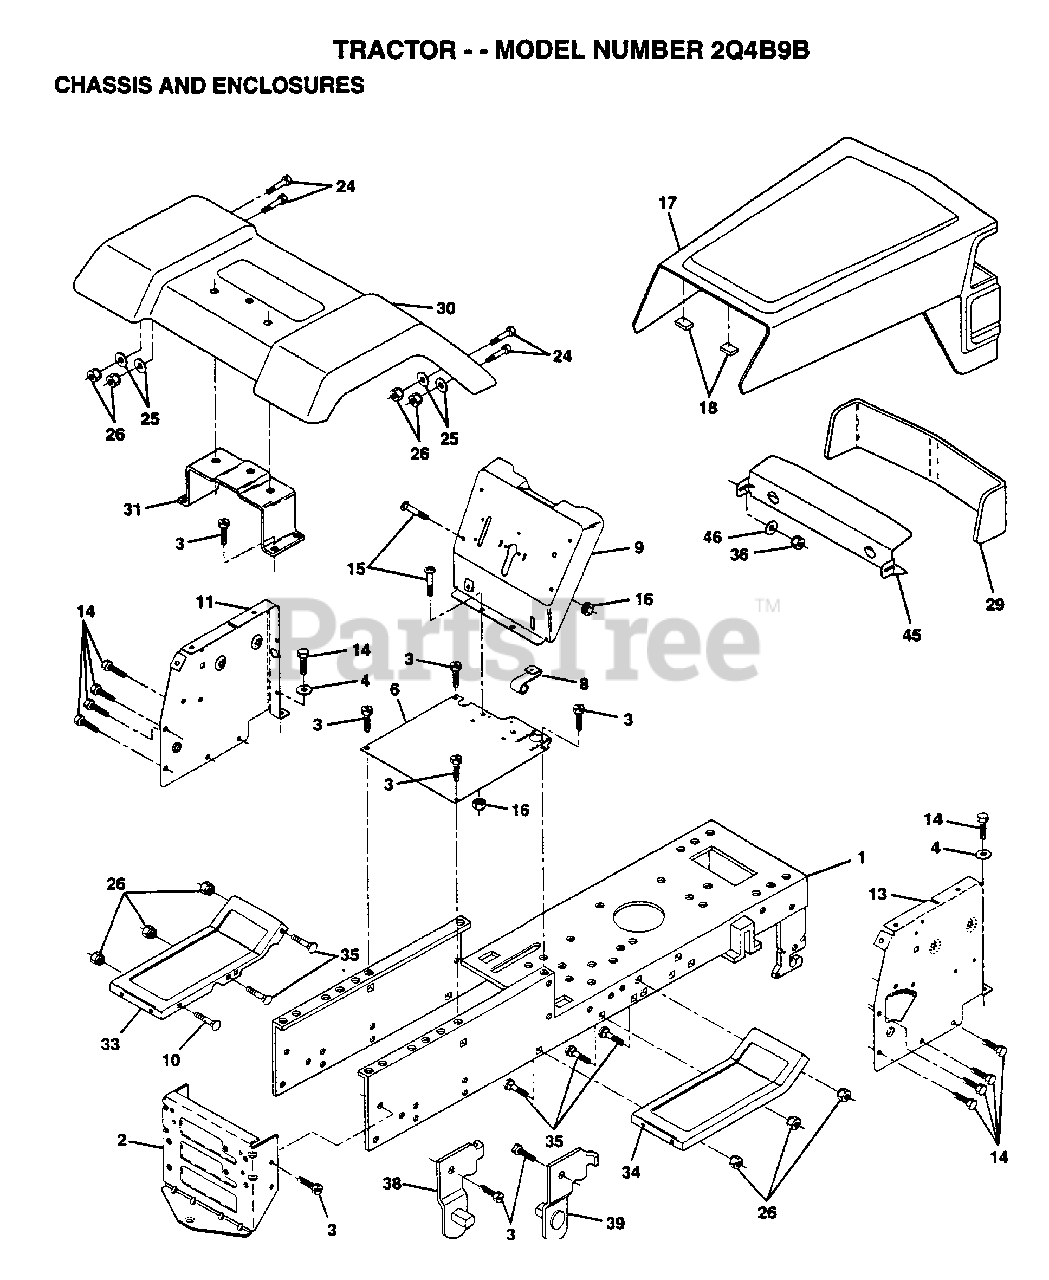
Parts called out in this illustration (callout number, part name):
1	CHASSIS.WLD.11GA
3	SCREW
4	WASHER
6	BLADE.20.MULCH.AY
8	"CLIP,INSULATOR"
9	DASH SILKSCRN 1
11	DASH PANEL LH
14	SCREW LT
15	SCREW
17	HOOD/GRILL ASM
24	BOLT
25	WASHER
26	NUT
31	BRKT FENDER
33	FOOTREST.LH.LT/GT
34	FOOTREST.RH.LT/GT
35	BOLT
36	PAL NUT LT
38	BRACKET ASM LH
39	BRACKET ASM RH
46	RETAINER
